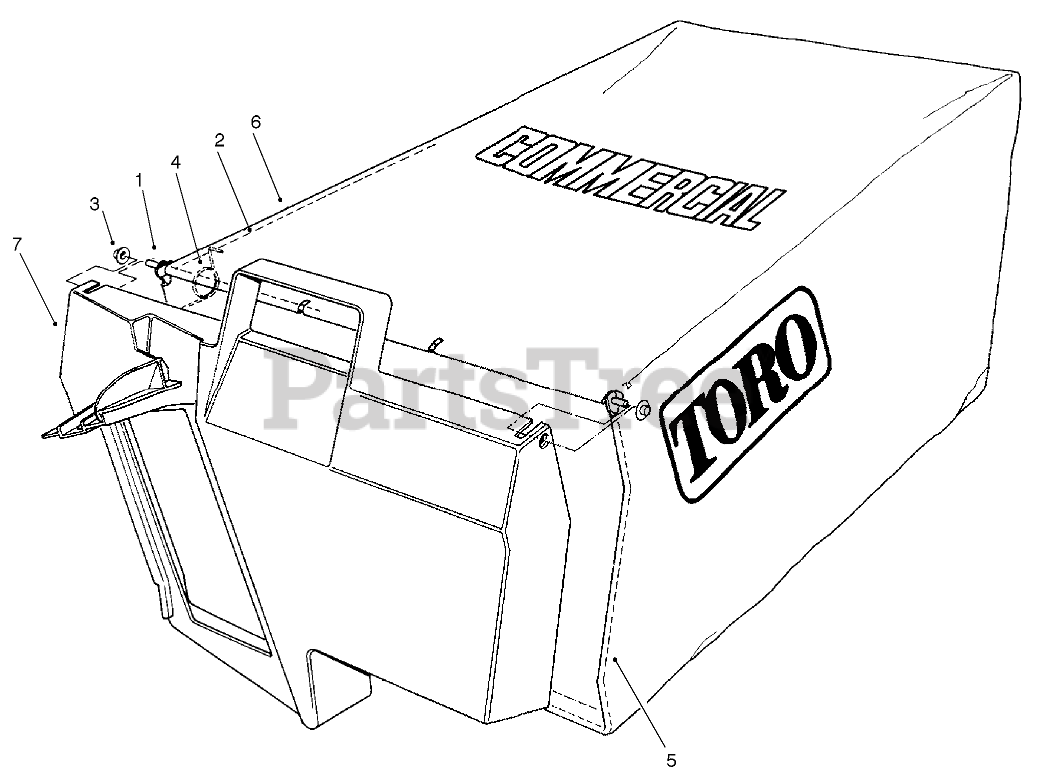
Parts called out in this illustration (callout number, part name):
1	HINGE-DOOR, BAG
2	FRAME-BAG, UPPER
3	NUT-PUSH
4	SPRING
5	FRAME-BAG
6	BAG-GRASS
7	DOOR-BAG, GRASS
